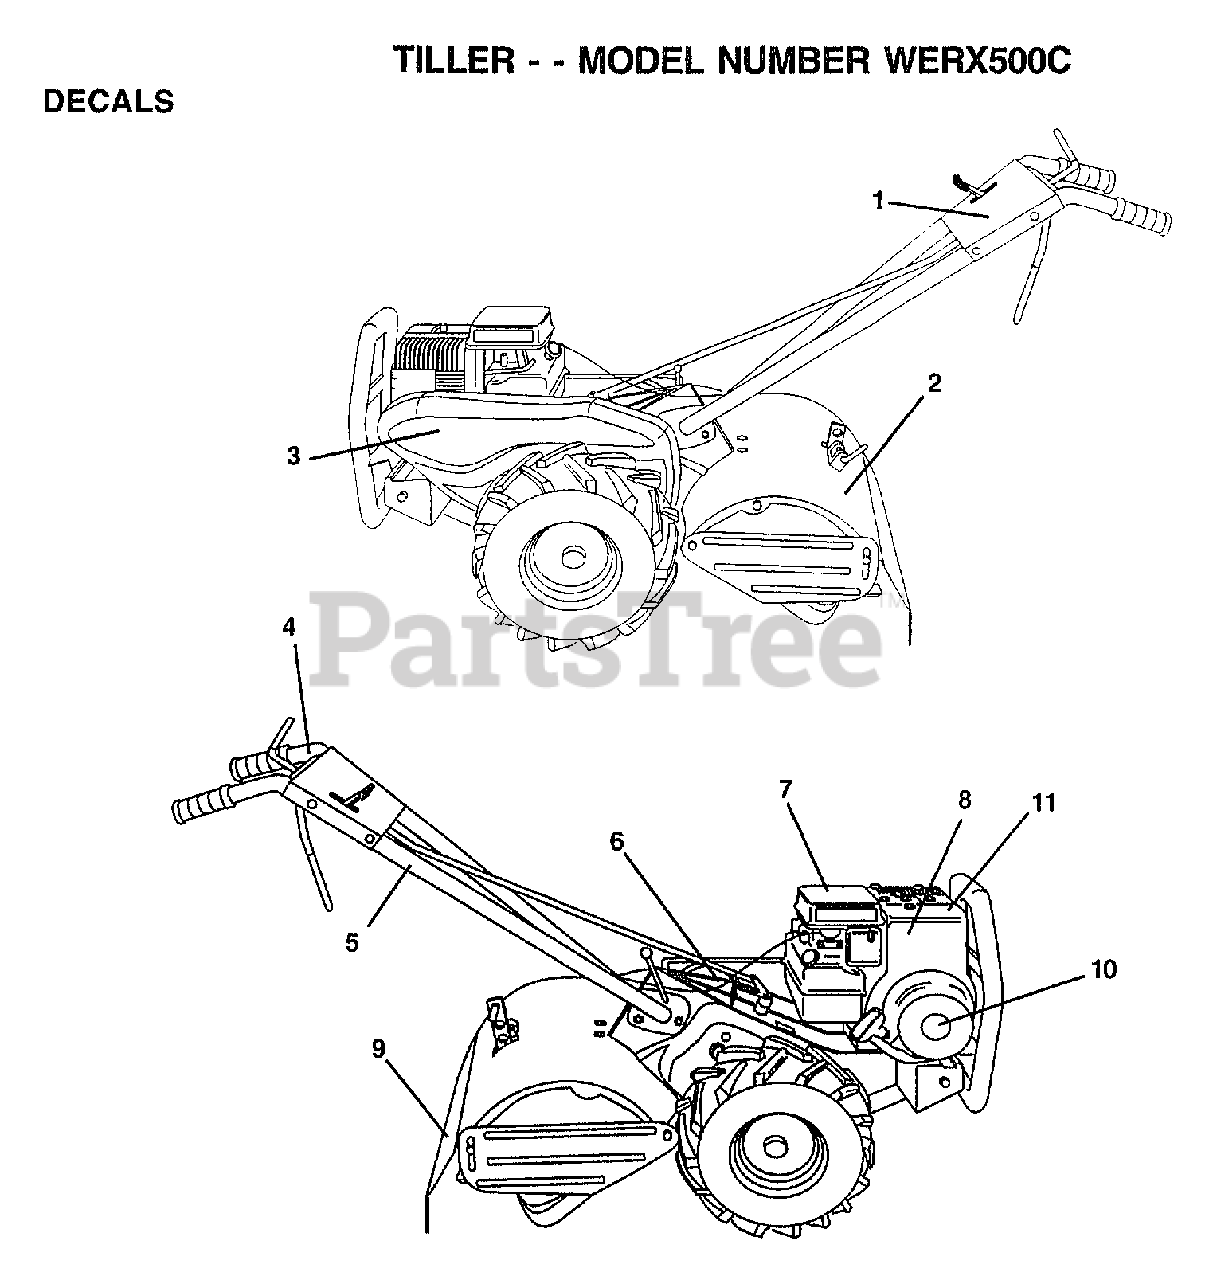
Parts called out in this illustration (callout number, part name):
2	DECAL.DESCRIPTION
3	"DECAL,LOGO"
5	DECAL-PLACEMENT
6	DECAL CRT
7	DECAL TI
8	DECAL
9	DECAL-WARNING
11	DECAL.EURO.ST.CE.
